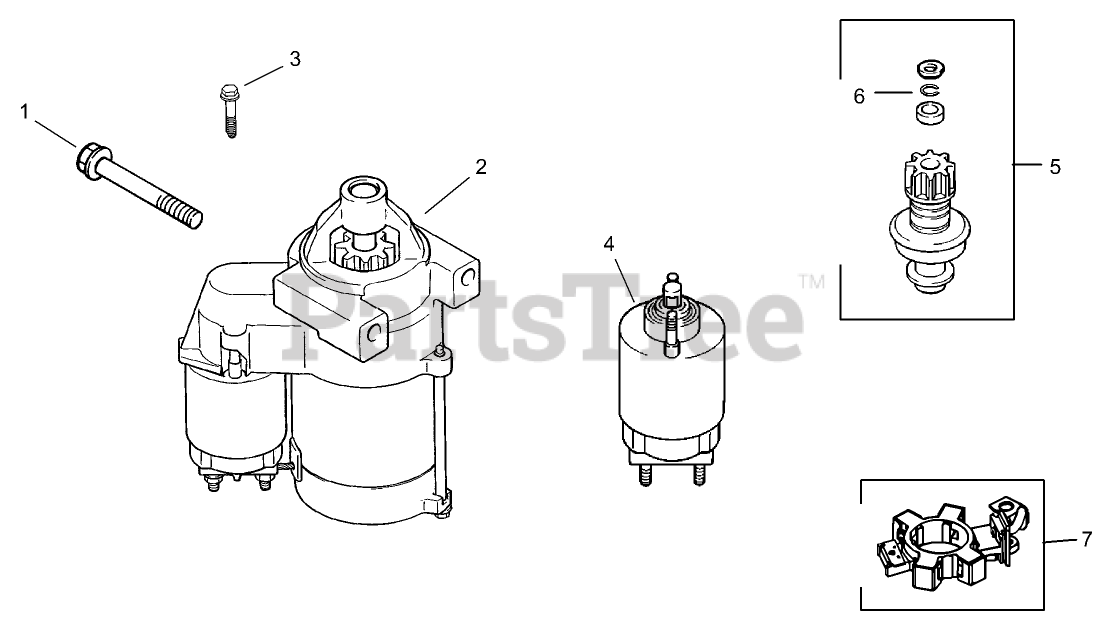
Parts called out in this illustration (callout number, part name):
1	SCREW-FLG (M8X1.25X80)
2	Starter assembly (Includes 3-8)
3	SCREW-TORX HEAD, EXTERNAL
4	Kit, solenoid (Incl. 3)
5	Kit, pinion drive (Incl. 6)
6	RING-RETAINING
7	BRUSH HOLDER KIT
